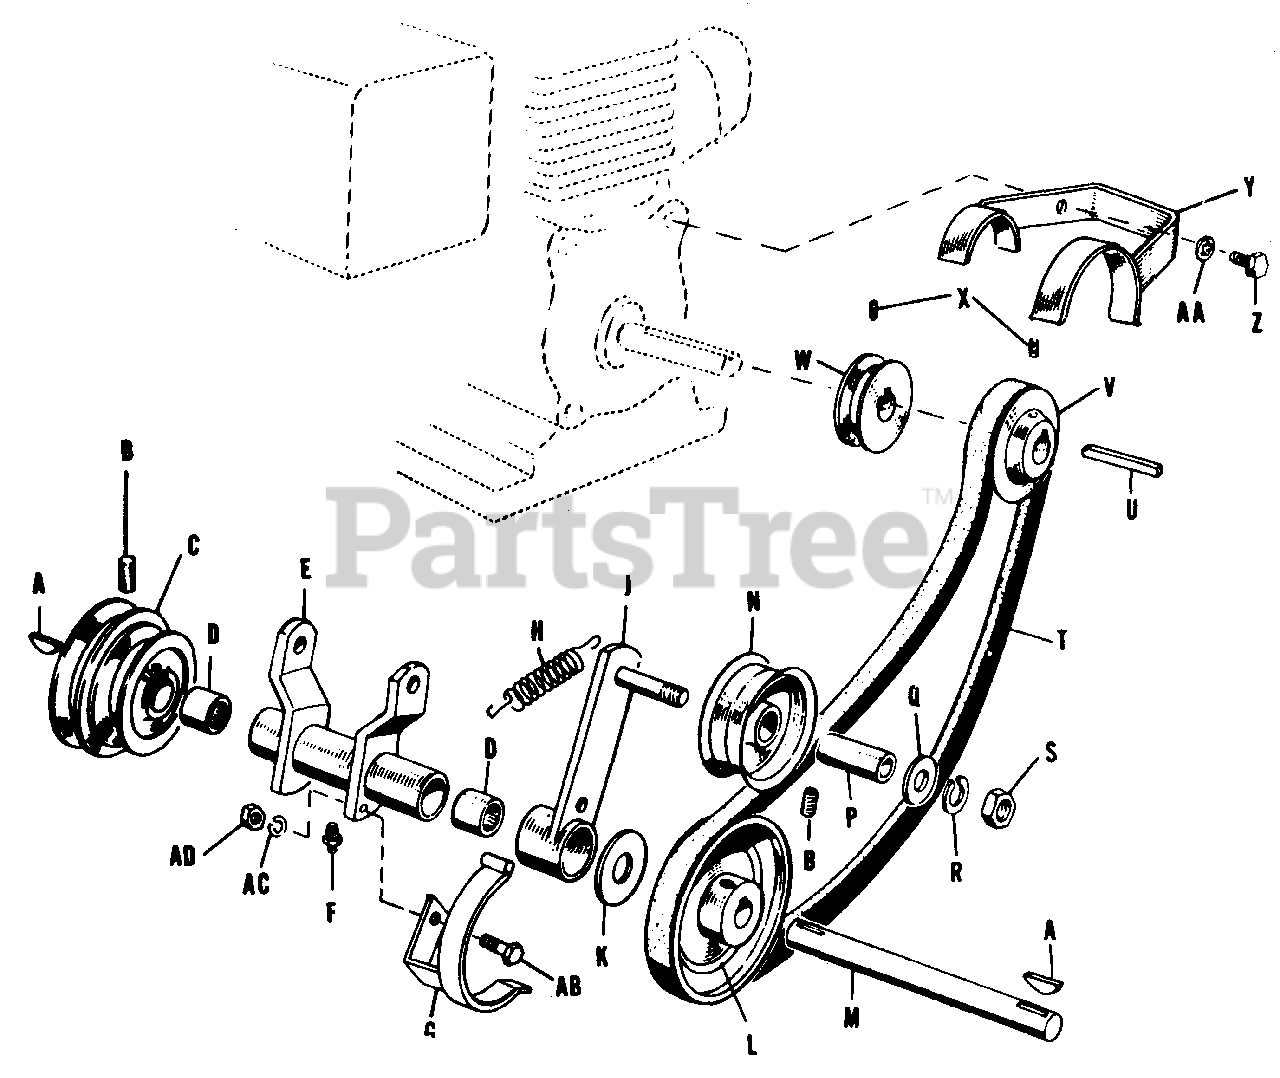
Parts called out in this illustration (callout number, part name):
A	Key, Woodruff, 3/16 x 3/4
B	Screw, Set, 5/16-18 x 1/2
D	Bearing, Needle
E	Bracket Assembly, Drive
F	Grease Fitting, Alemite #1641
G	Retainer, Belt
J	Lever, Idler Assembly
M	Shaft, Idler
N	Pulley, Idler
P	Race, Inner Bearing
Q	Washer, Plain, 3/8
R	Washer, Lock, 3/8
S	Nut, Full Hex, 3/8-16
U	Key, Engine Pulley
V	Pulley, Engine to P.T.O.
W	Pulley, Engine to Transmission
X	Screw, Set, Cup Point, Socket Hd., 5/16-18 x 5/16
Y	Bracket Assembly, Belt Guard
Z	Capscrew, Hex Hd., 1/2-20 x 3/4
AA	Washer, Lock, 1/2 Internal Shakeproof
AB	Capscrew, Hex Hd., 1/4-20 x 3/4
AC	Washer, Lock, 1/4
AD	Nut, Full Hex, 1/4-20
